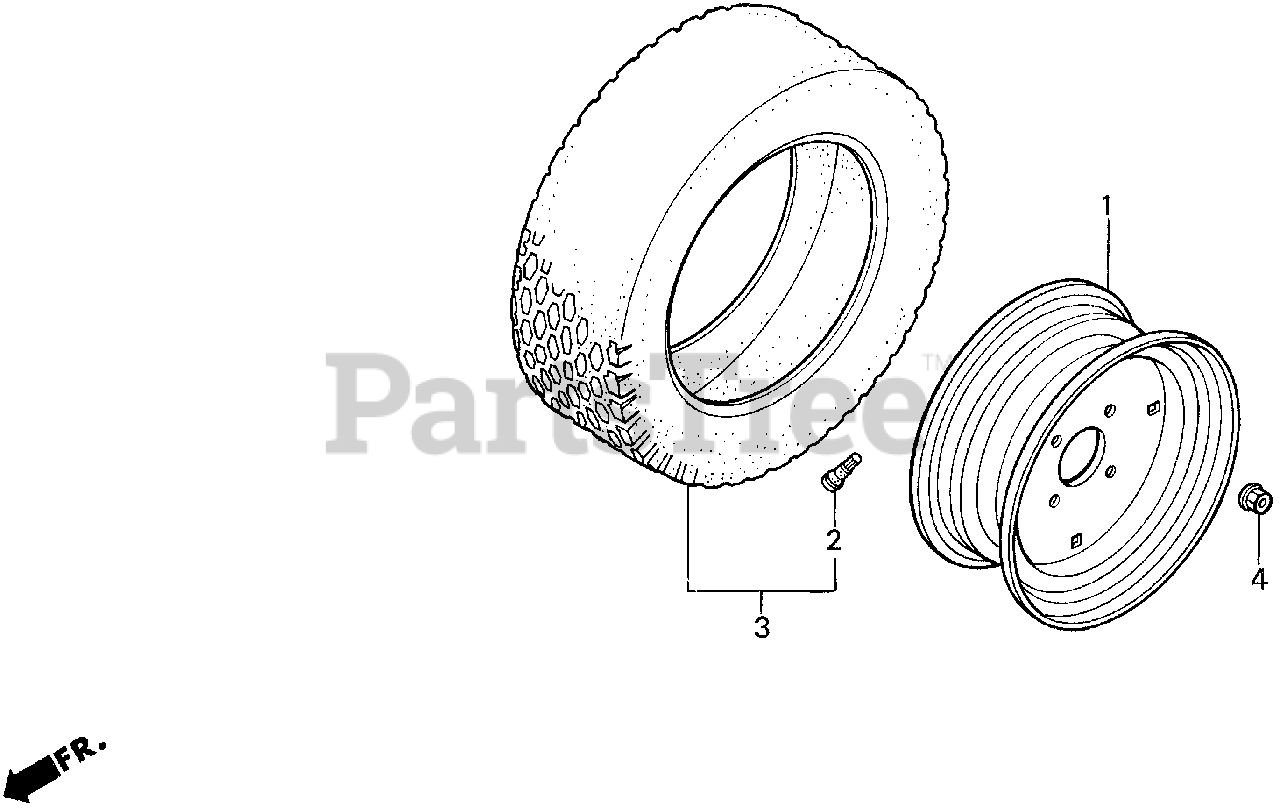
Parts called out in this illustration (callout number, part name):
1	WHEEL (5JAX12WDC) *NH35M* (CLOUD SILVER METALLIC)
2	VALVE, RIM
3	TIRE ASSY., FR. (20X7.00-12) (2PR)
4	NUT, WHEEL (12MM)
